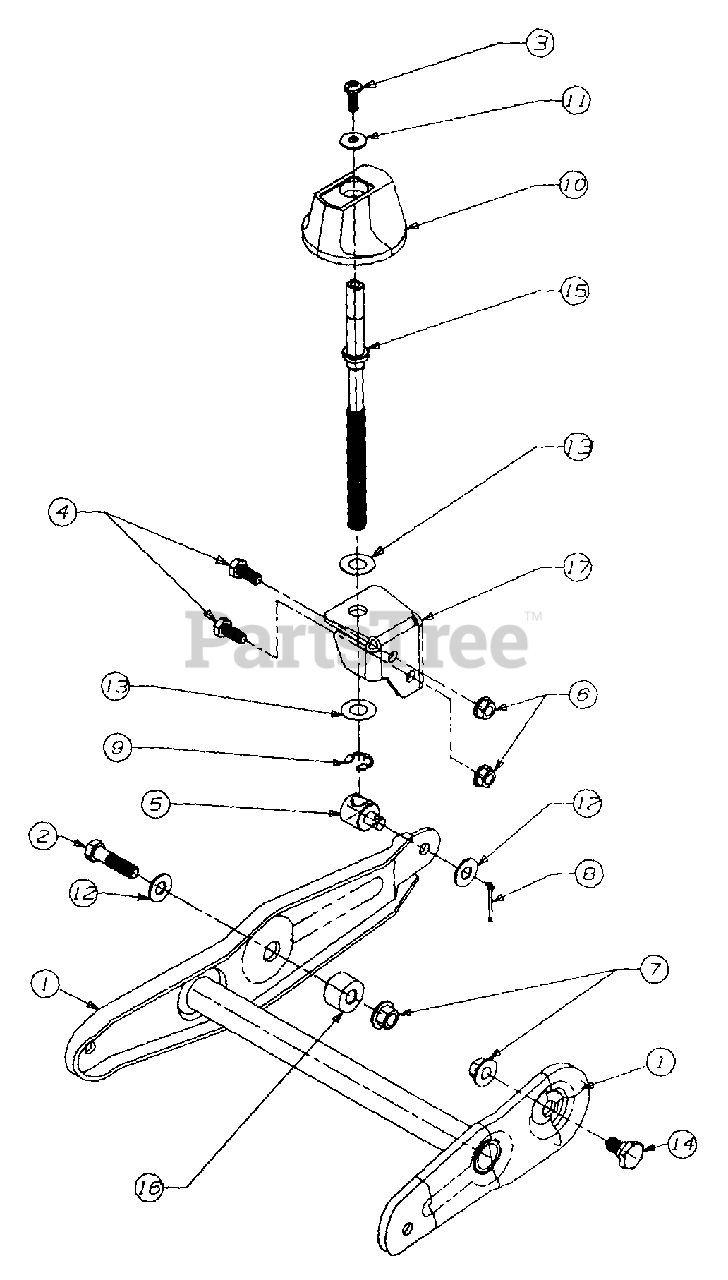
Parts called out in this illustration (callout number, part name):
3	SCREW - MACHINE PAN HD
4	SCREW-HEX
5	FERRULE - ADJUSTABLE
6	NUT-HEX FLANGE
7	NUT-HEX FLANGE LOCK
8	PIN-COTTER
9	RING-E
10	KNOB-PLASTIC
11	WASHER-BELL
12	WASHER-FLAT
13	WASHER-FLAT
14	SCREW-SHOULDER
15	ROD-ADJUSTABLE
